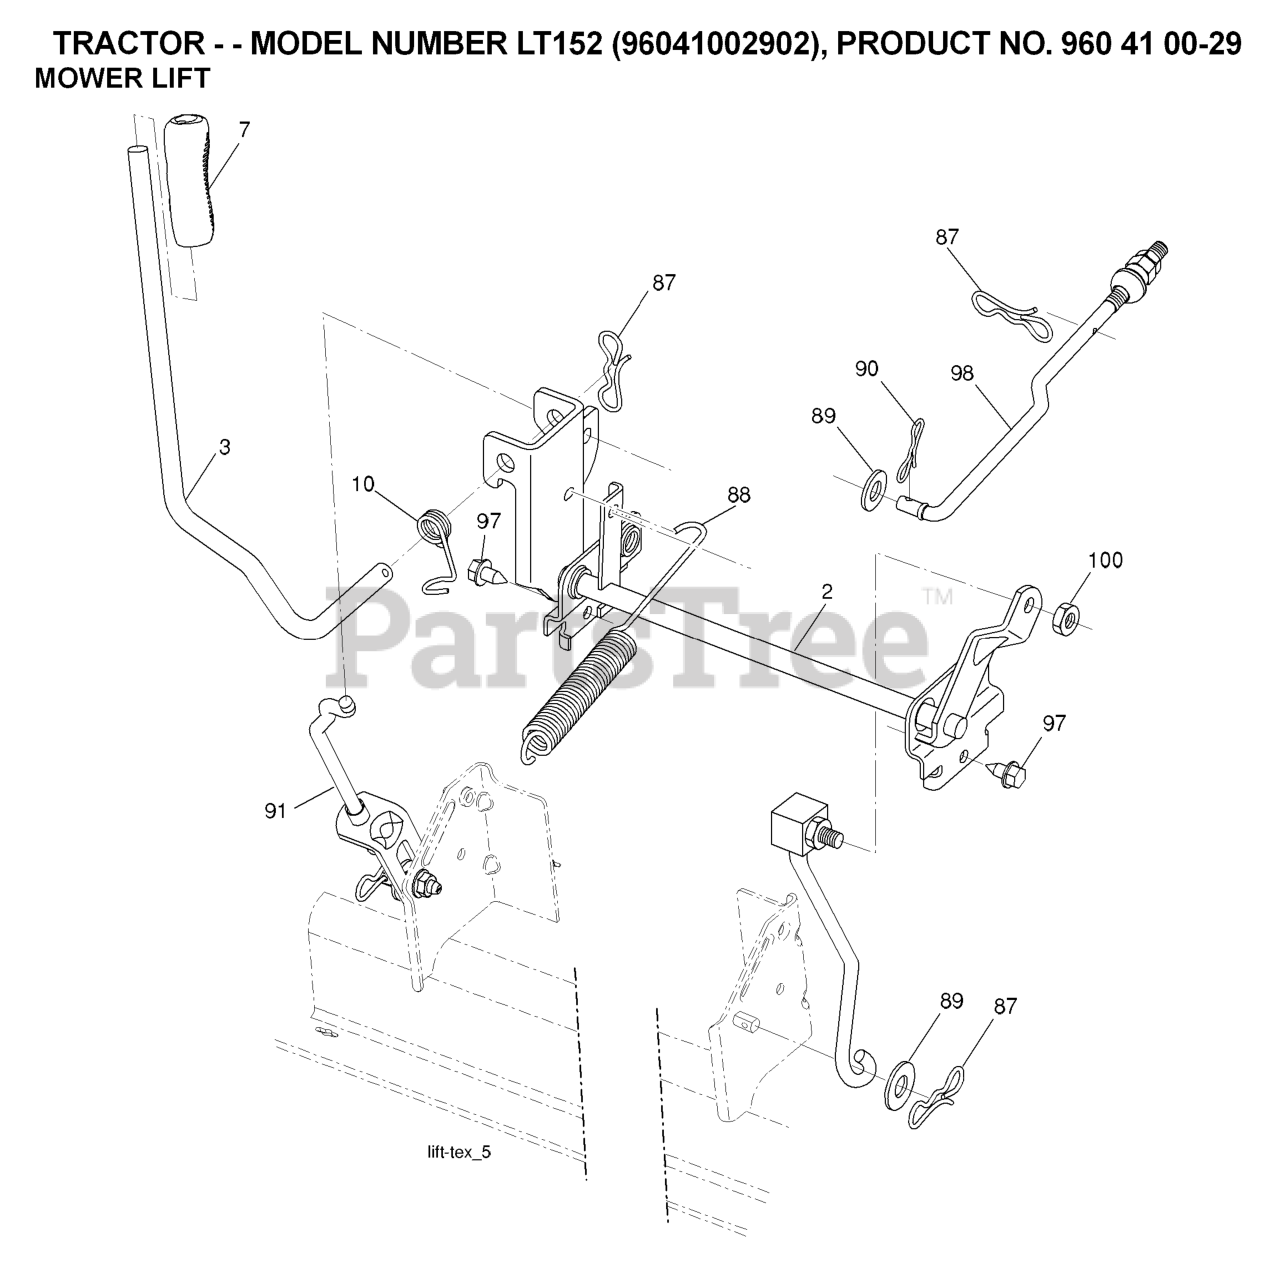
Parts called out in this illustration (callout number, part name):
2	SHAFT.ASM.LIFT.CROSS.H
3	LEVER.LIFT.HANDLE.LT
7	GRIP.HANDLE.LIFT.PVC.BLACK
10	SPRING.TORSION.LIFT.HANDLE
87	PIN.COTTER.7/16.BOW TI.
88	SPRING.LIFT.ASSIST
89	WASHER.CLEAR.ZINC
90	PIN.COTTER.5/16.BOW TI
91	LINK.ASM.LIFT.REAR
97	SCREW 3/8-16X3/4
98	LINK.ASM.SUSP.FRONT.MW
100	LOCKNUT
